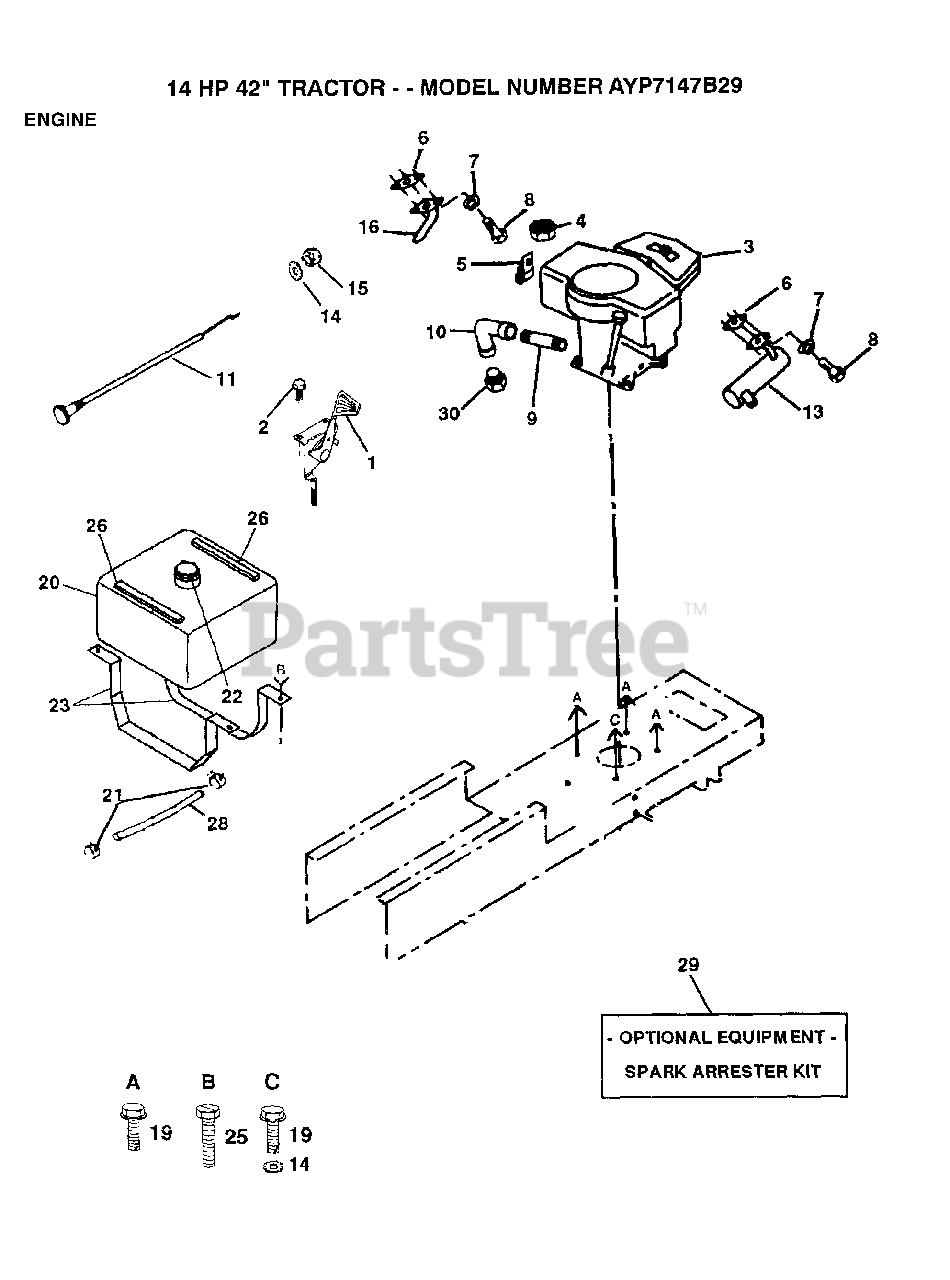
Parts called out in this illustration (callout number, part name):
2	SCREW LT
4	NUT
5	CLIP T
7	LOCKWASHER
9	PIPE NIPPLE LT
10	ELBOW
11	CHOKE CONTROL
12	WASHER
14	LOCKWASHER
16	EXHAUST TUBE T
19	SCREW
21	HOSE CLAMP
23	"STRAP,TANK"
25	SCREW LT
26	"STRIP,FORM"
28	HOSE T
